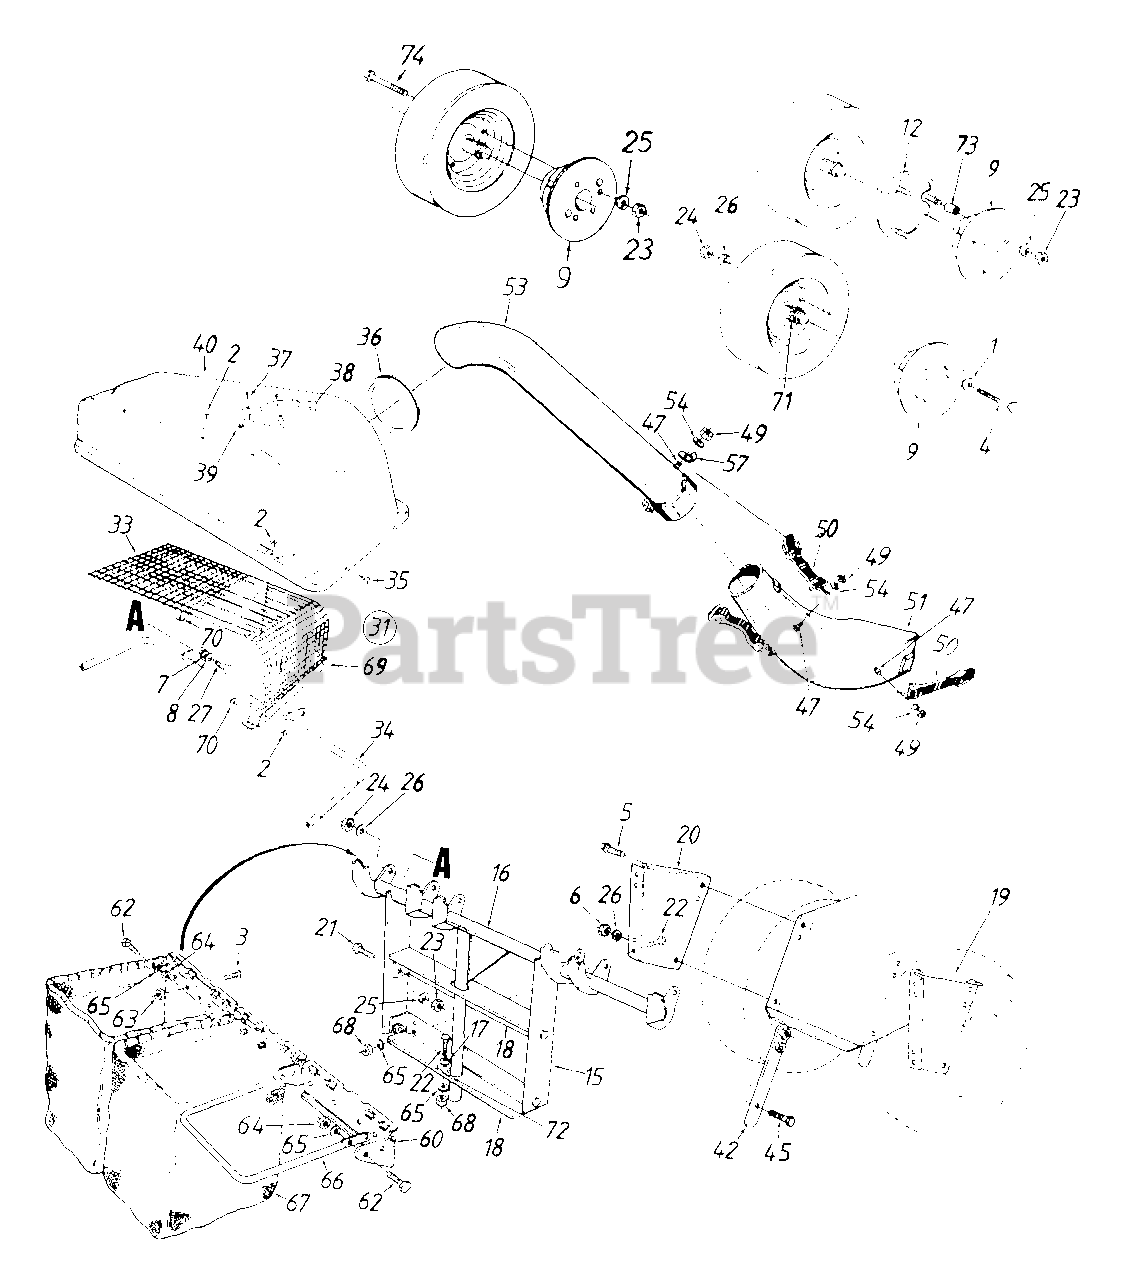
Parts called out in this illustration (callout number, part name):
1	Fl-Wash, .385" I.D.
2	Pop Rivet
3	Truss Mach. Scr. #10-24 x .38" Lg
4	Hex Bolt 3/8-16 x 4.5" Lg.
5	Hex Wash. Hd. Tap Scr. 5/16-18 x .62"
6	Hex Nut 3/8-24 Thd.
7	Bell-Wash. .515" I.D.
8	Fl-Wash. .510" I.D.
15	Catcher Support Tube Mtg. Brkt.
16	Catcher Support Tube Ass'y,
17	Bell-Wash. .265" I.D.
18	Catcher Latch and Support Brkt.
21	Hex Belt 5/16-18 x .75" Lg.
22	Hex Bolt 1/4-20 x .62" Lg. - Grade 5
23	Hex Nut 5/16-18 Thd.
24	Hex Nut 3/8-16 Thd.
25	L-Wash. 5/16" I.D.
26	L-Wash. 3/8" I.D.
27	Shld. Bolt 3/8-16 x .500" Dia.
28	Bell-Wash. .505" I.D. x 1.00" O.D.
31	Grass Catcher Cover Ass'y. Comp.
33	Screen
34	Hinge Brkt. Ass'y.
35	Hex Tap Scr, 1/4-20 x .5" Lg.
36	Tube Seal
37	Truss Mach. B-Tap Scr. #10 x .5" Lg.
38	Plastic Plate
39	Speed Nut
40	Grass Catcher Cover
47	Hex Bolt 1/4-20 x 50" Lg.
49	Hex Ins. L-Nut 1/4-20 Thd.
50	Retainer Strap Ass'y.
51	Discharge Chute
53	Catcher Elbow Tube
54	L-Wash. .270" I.D. x .57" O.D.
57	Retainer Hook Brkt.
60	Bag Frame Hanger Brkt.
62	Hex Bolt 1/4-28 x .75" Lg.
63	Hex Sems Nut #10-24 Thd.
64	Hex Nut 1/4-28 Thd.
65	L-Wash. 1/4" I.D.
66	Catcher Bag Frame
67	Grass Catcher Bag
68	Hex Nut 1/4-20 Thd.
71	Foam Strip 1-1/8" x 1-1/2" x 3/8"
72	Support Tubing Adapter Brkt.
73	Spacer
74	Hex Bolt 5/16-18 x 4" Lg.
